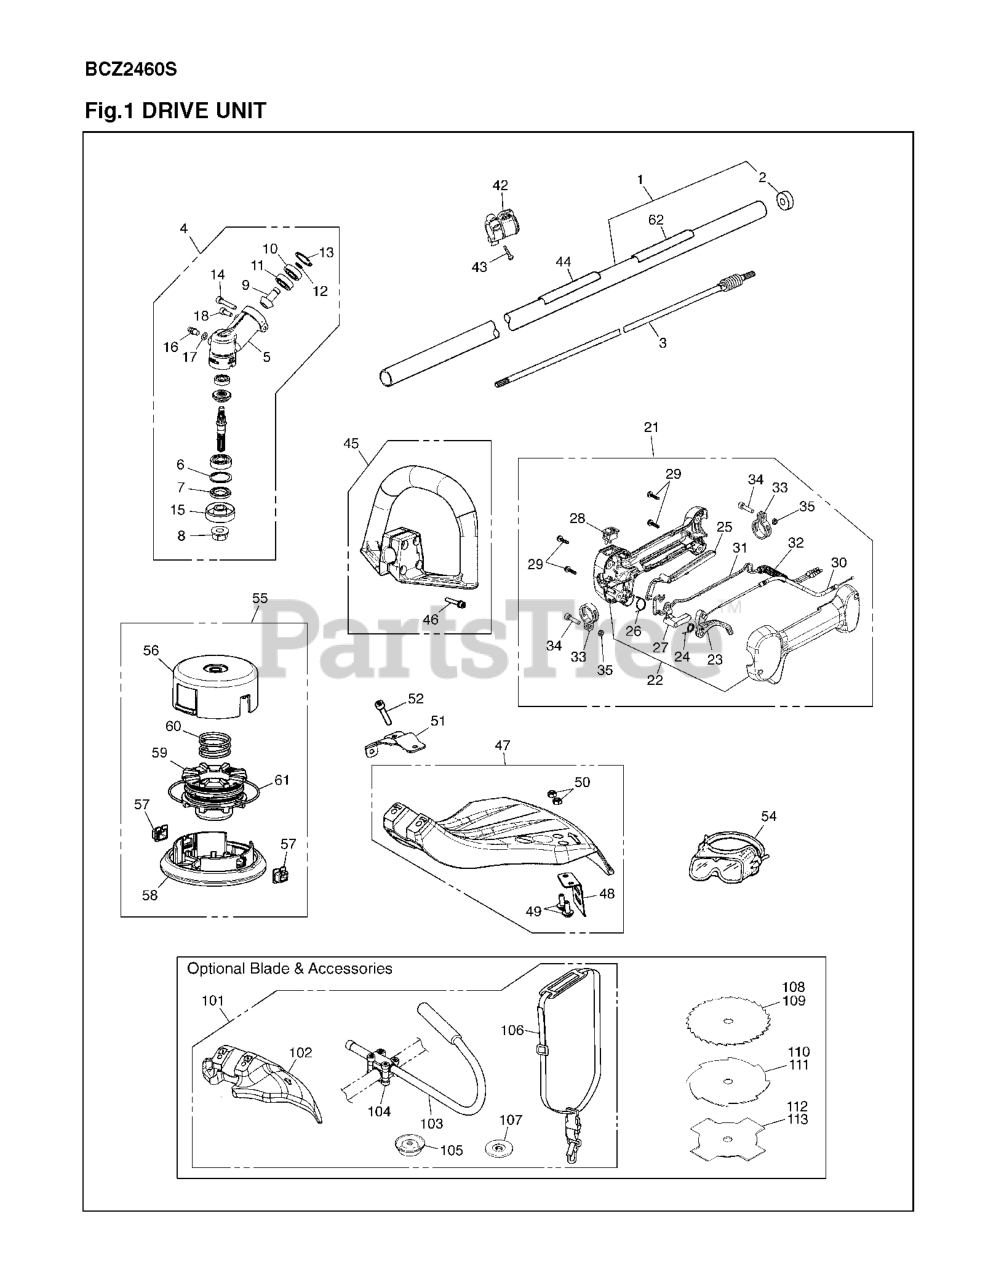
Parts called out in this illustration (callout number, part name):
1	PIPE COMP
4	GEARCASE
5	GEARCASE
6	RING,SNAP M26x1.2 RP-318013340
7	SEAL, OIL(RPLS 3565-13131)
11	BALL BEARING
13	RP_RING
14	BOLT, TORX
15	HOLDER (A)
16	FITTING, GREASE
18	BOLT, TORX
21	GRIP ASSY
22	GRIP HALF SET
23	LEVER, THROTTLE
24	SPRING, THROTTLE
25	LEVER FOR GRIP (RPLS -0600)
26	SPRING JOINT
27	LEVER JOINT
31	CORD - C
34	SCREW
35	NUT
42	HANGER COMP.
43	SCREW
44	LABEL CAUTON FOR BC
45	HANDLE ASSY. (RPLS T319514001)
46	SCREW
47	GUARD ASSY
49	SCREW
52	BOLT, TORX
54	GOGGLExxx (RPLS
56	CASE (RPL T318915112)
57	EYELET
58	COVER (RPLS T318915131)
59	HOLDER, CORD (RPLS T318915141)
61	CORD
62	NAME PLATE BCZ2460S
101	BLADE KIT BCZ 24/26/30 SERIES
103	J-HANDLE
104	BRACKET ASSY.
105	COVER(10mm)(RPL280,-13280)
106	STRAP ASSY
107	HOLDER (B)
108	Brushcutter Blade, 22 Tooth 9"
109	Brushcutter Blade, 24 Tooth 9"
110	BLADE, 8
111	Brushcutter Blade, 8 Tooth 9"
112	BLADE, 8
113	Brushcutter Blade, 4 Tooth 9"
